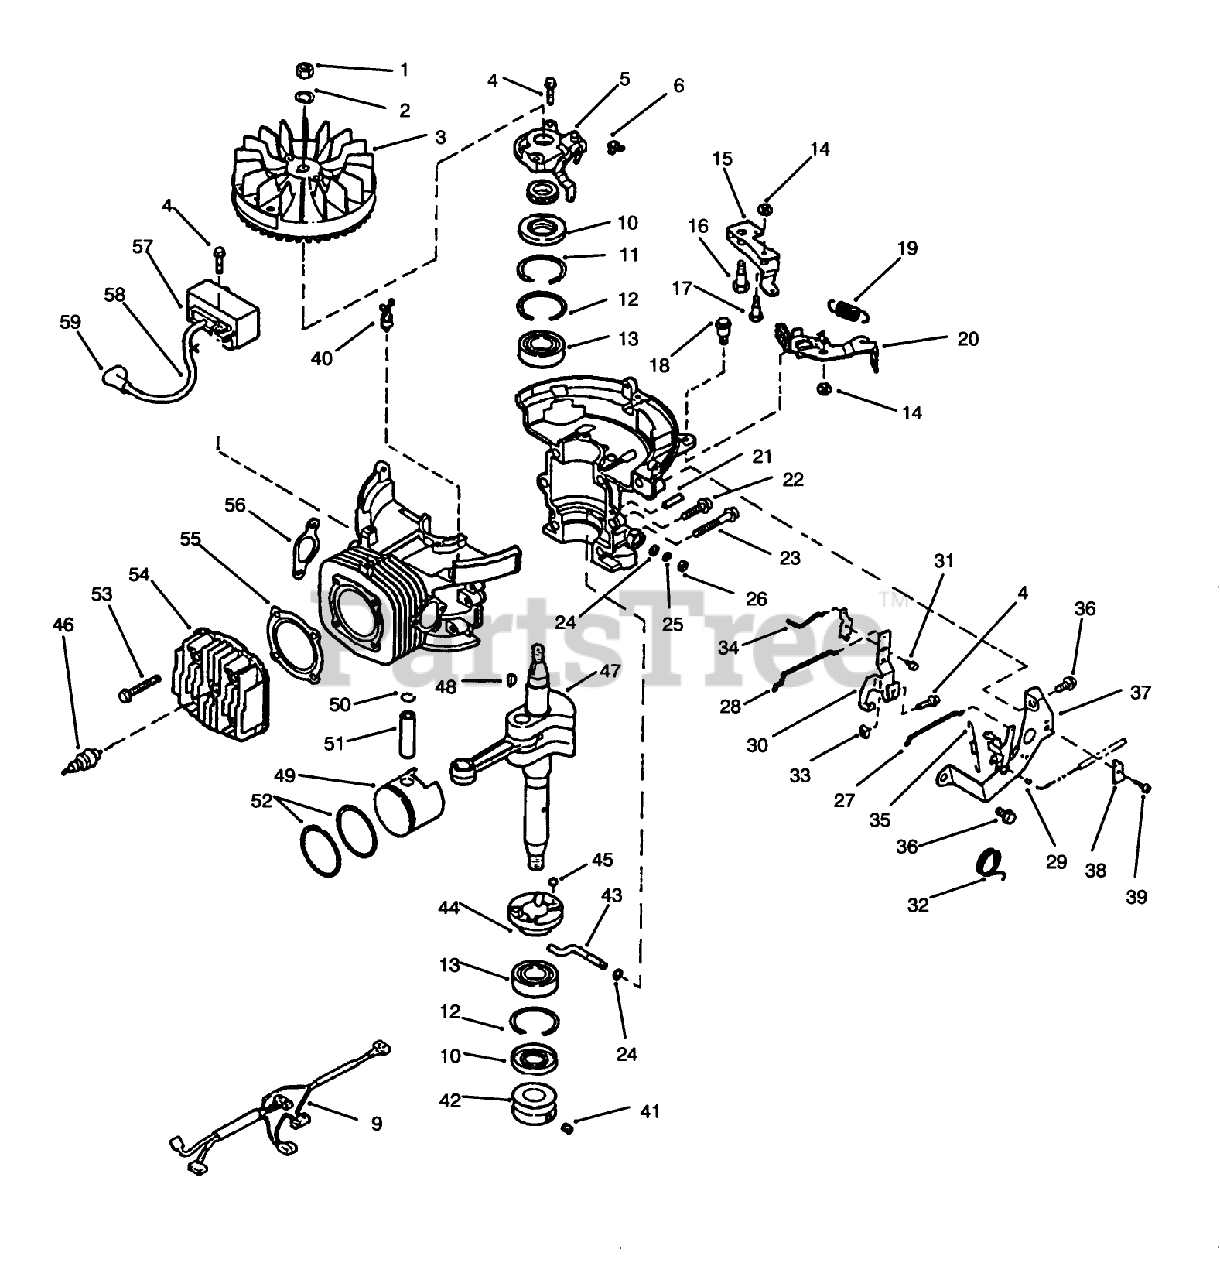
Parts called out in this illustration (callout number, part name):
3	FLYWHEEL AY SM
9	WIRE HARNESS SM
10	SEAL - OIL SM
11	RING-RETAINER SM
13	BEARING-BALL SM
14	LOCKNUT E
15	ACT.BRAKE LVR. SM
16	STUD-SHOULDER SM
19	SPRING-BRAKE
22	SCREW-H.W.HD. F
23	SCREW-HEX W.H. SM
25	RING-RETAINING
26	SEAL - OIL SM
28	ROD-THROTTLE SM
35	SPRING-GOV. SM
37	GOVNR BRKT SM
40	WIRE TIE SM
42	PULLEY-ENGINE
52	RING SET S
54	CYLINDER HEAD SM
56	GASKET - EXH SM
58	HI-TENS.LEAD
59	COVER & TERM. AY S
